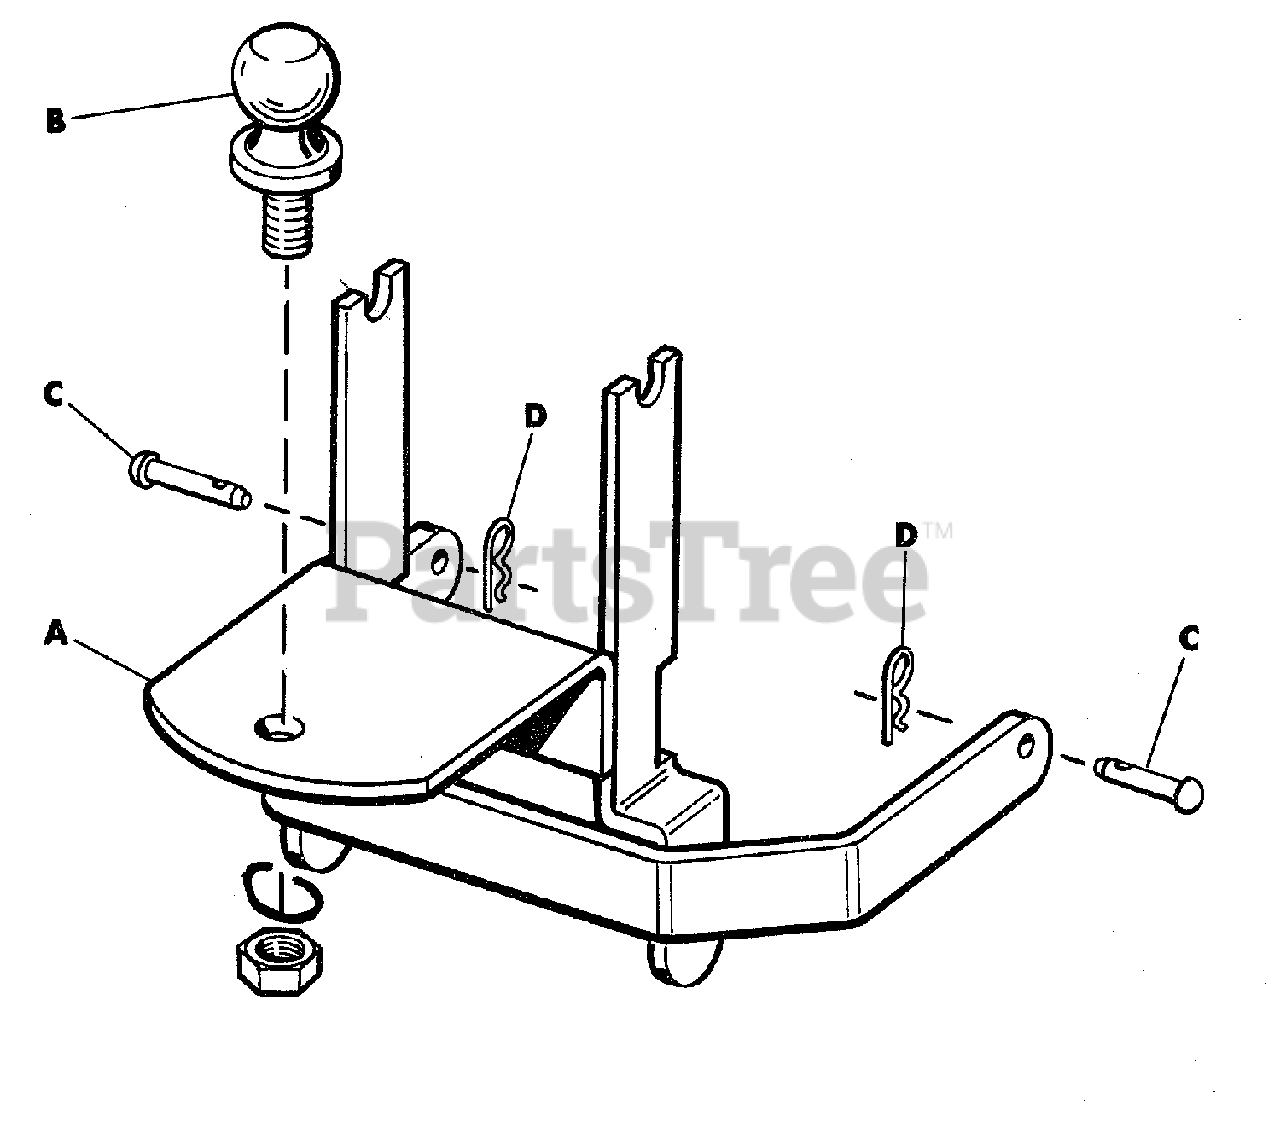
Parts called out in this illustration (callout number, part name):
A	HITCH ASSEMBLY
B	BALL, Hitch
C	PIN
D	CLIP, Spring
